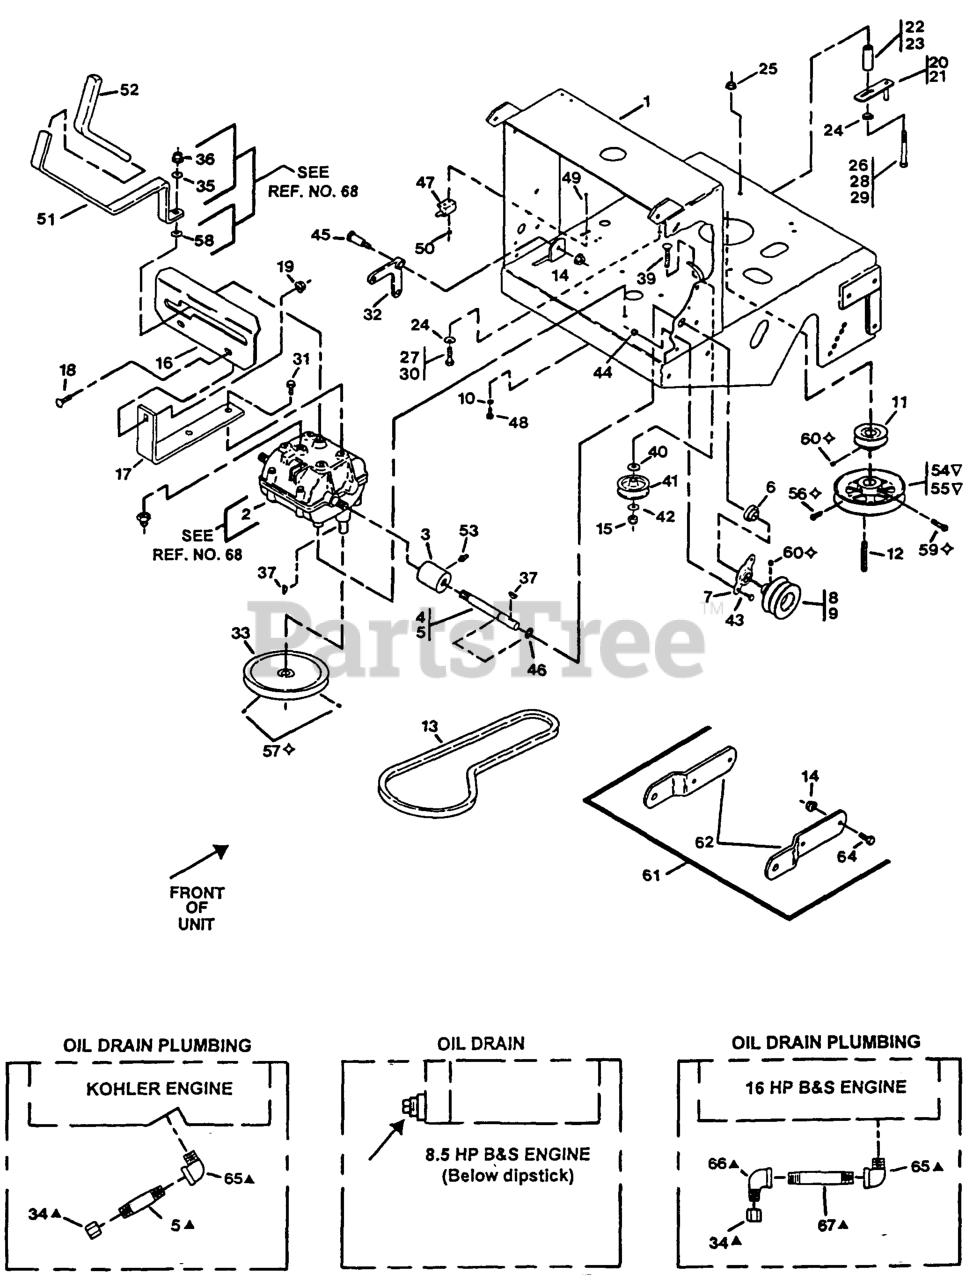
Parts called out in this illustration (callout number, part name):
5	NIPPLE
6	BEARING-SHAFT
7	FLANGE-OUTPUT
10	WASHER-LOCK
11	SHEAVE-TRANSMISSION
12	KEY,MACH 1/4X1/4X2-5/8
13	BELT,TRANS DRIVE
17	BRACKET-PLATE, SHIFT
20	GUIDE-BELT
21	GUIDE-BELT
24	WASHER-SPRING
28	SCRW,CAP HH M8X1.25X75M
29	SCRW,CAP HH M8X1.25X75M
32	BELLCRANK
33	SHEAVE-TRANSMISSION
34	CAP-HEX
38	SWITCH-START, NEUTRAL
45	BOLT-SHOULDER
47	SWITCH-OPEN, NORMALLY
54	SHEAVE,BLADE DRIVE
56	SCREW-SET
60	SCREW-SET
61	Sulky Hitch Kit, Metro
62	HITCH-SULKY
65	FITTING-ELBOW-90
66	ELBOW-90 DEG
67	NIPPLE
